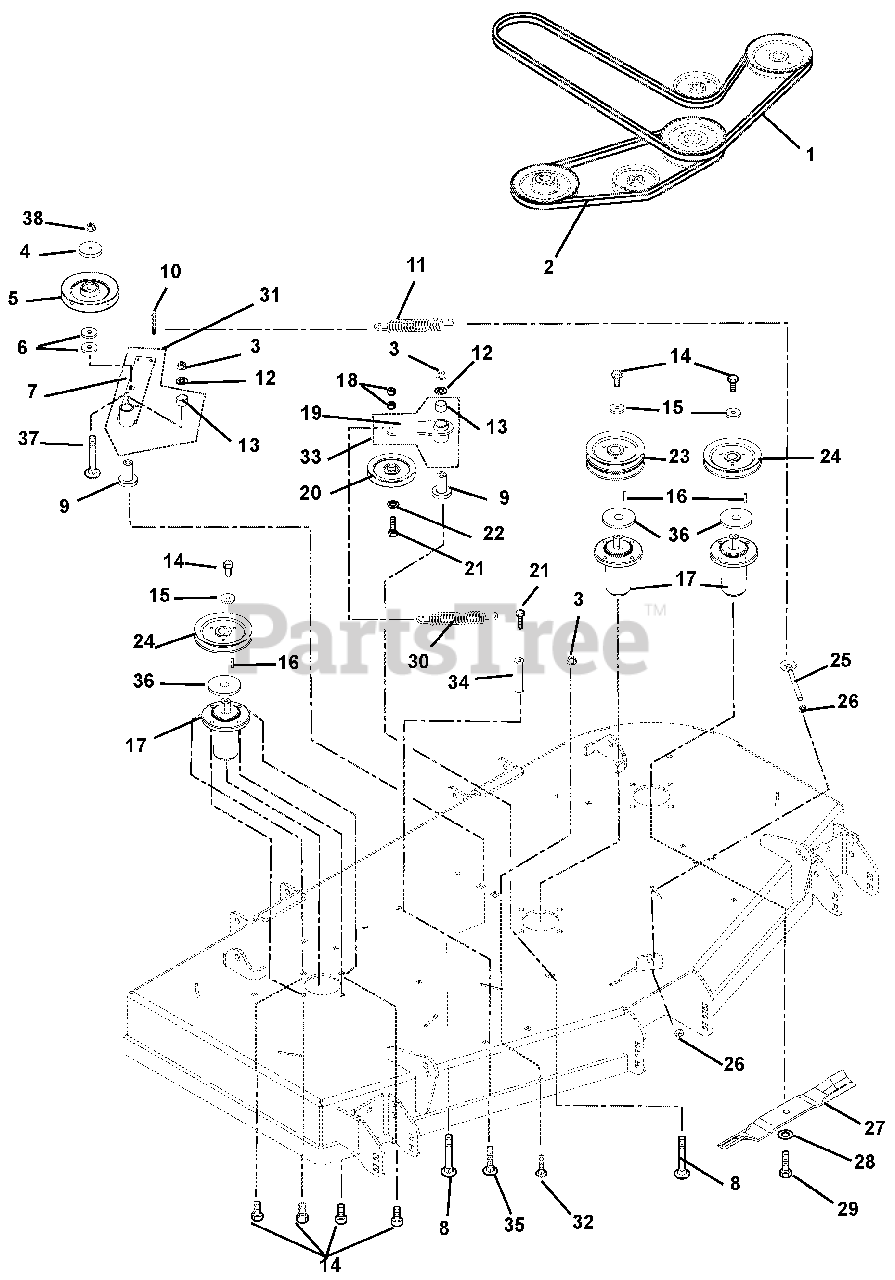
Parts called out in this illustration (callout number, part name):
1	Belt, 175" Long, PTO Drive Hex (992322)
2	V-Belt, 56" Long Cog B-Section (992322)
3	Nut, .50-13 Nyloc Flange
4	Cap, Idler Bearing Sealing
5	Pulley, V 6.0 x .500 ID DBL. Bearing (SN 000101 – 002999)
6	Washer, Flat Stee,l .515 x 1.625 x .250
7	Idler, Pivot Arm
8	Bolt, Round Head Square Neck .50-13 x 3.50
9	Bearing, Pedestal
10	Bolt, Shoulder EP .38-16 x .30 Hex
11	Spring, Extension (Deck Idler)
12	Washer, Flat Steel .531x 1.250 x.100
13	Bushing, 1.00 x 1.125 x 1.936
14	Bolt, Hex .38-16 x 1.00
15	Washer, Flat Steel .406 x 1.50 x .245
16	Key, Square .25 x .25 x 1 RC 40-50
17	Spindle Assembly
18	Nut, Locking-Center .38-16
19	Idler, Pivot Arm
20	Assembly, V-Idler 5.00 O.D.
21	Bolt, Hex .38-16 x 2.25
22	Washer, Flat Steel .406 x .812 x .065
23	Sheave, Double 1" ID x 6.00" OD (992322)
24	Sheave, Single 1" ID x 6.00" OD (992322)
25	Bolt, .38-16 x 4.50 .62 Diameter Eye
26	Nut, Hex, Jam .375-16
27	Blade, 18.00" Mower, Mulch (992322)
28	Washer, Bellville .63 x 1.625 x.14
29	Bolt, Hex .62-18 x 1.75 Grade 8
30	Spring, Extension
31	Assembly, PTO Idler Pivot Arm (Includes item # 7 and item # 13)
32	Bolt, Round Head Square Neck .50-13 x 1.5, Full Thread, Grade 5
33	Assembly, Idler Pivot Arm (Includes item # 13 and item # 19 )
34	Nut, Coupling .375-16 x 1.75
35	Bolt, Round Head Square Neck .38-16 x 1.00
36	Retainer, Grease
37	Bolt, Round Head Square Neck .50-13 x 3.00 Grade 5
38	Nut, Locking Center .50-13
